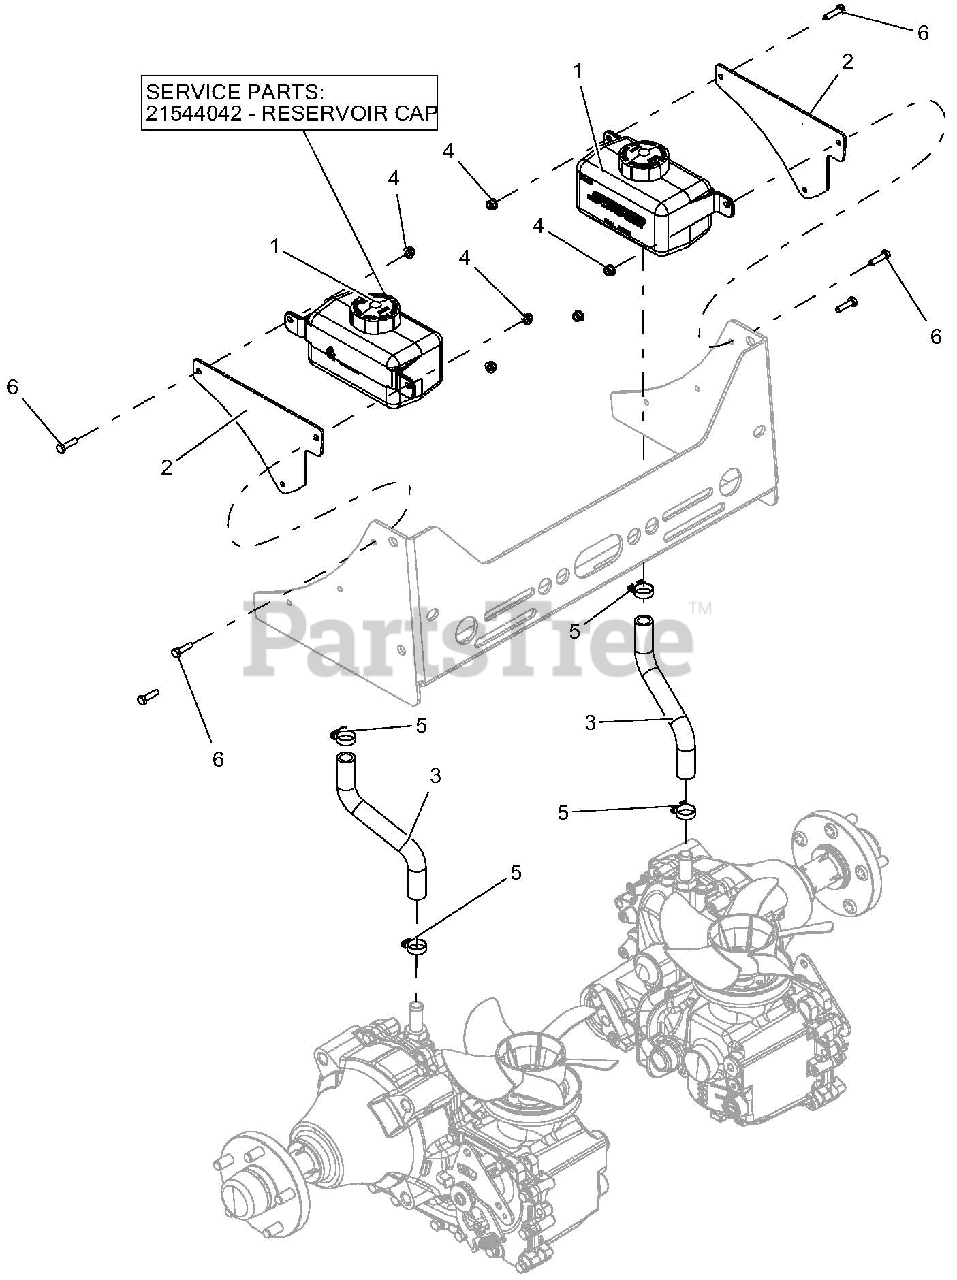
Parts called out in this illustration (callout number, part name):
1	TANK, HYD 1000ML
1	Reservoir Cap
2	PLATE, HYDRO OVERFLOW TANK MTG
3	HOSE, HYDRO OVERFLOW
4	NUT-LK-NYL-FLG .25-20 YWZC
5	CLAMP, .88 DIA HOSE
6	BLT-HEX .25-20 X 1.00 GR5 YWZC
